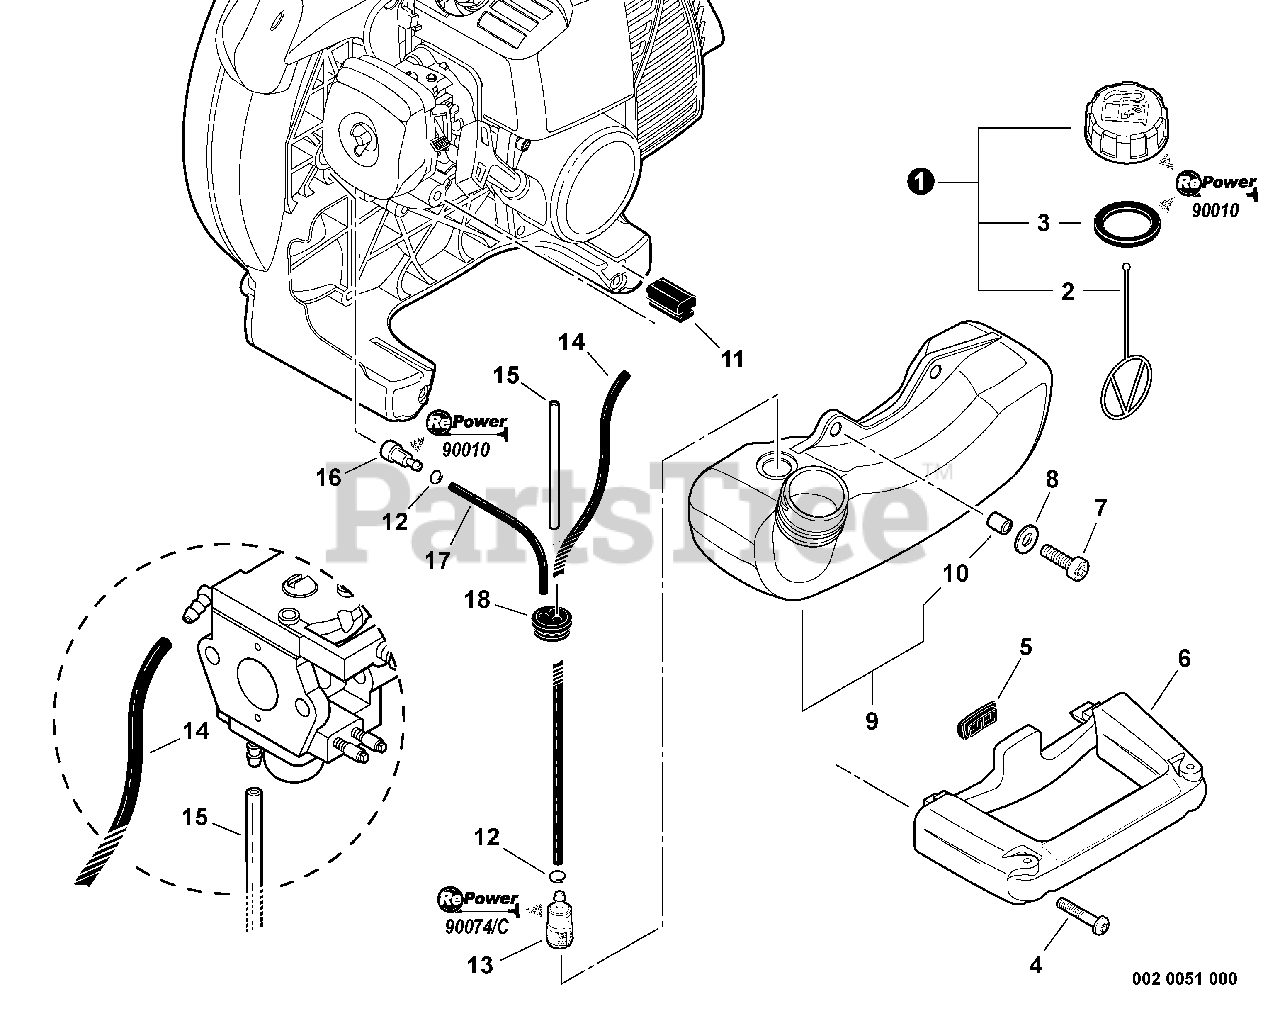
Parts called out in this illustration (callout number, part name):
1	CAP ASSY, FUEL
2	CONNECTOR, CAP L= 100 MM
3	GASKET, FUEL CAP
4	BOLT, TORX 5×25
5	CUSHION
6	HANDLE, REAR
7	BOLT, TORX 5×16
8	WASHER 5.5×12×0.8
9	TANK ASSY, FUEL
10	SPACER 6.2×7.8×6
12	CLIP 6 MM
13	FILTER, FUEL
14	PIPE, FUEL 3×5×210 BLACK
15	PIPE, FUEL 3×6×85 CLEAR
16	VENT ASSY
17	PIPE, FUEL 3×5×80 BLACK
18	GROMMET, FUEL
19	TUNE-UP KIT - REPOWER
20	CAP/VENT KIT - REPOWER
